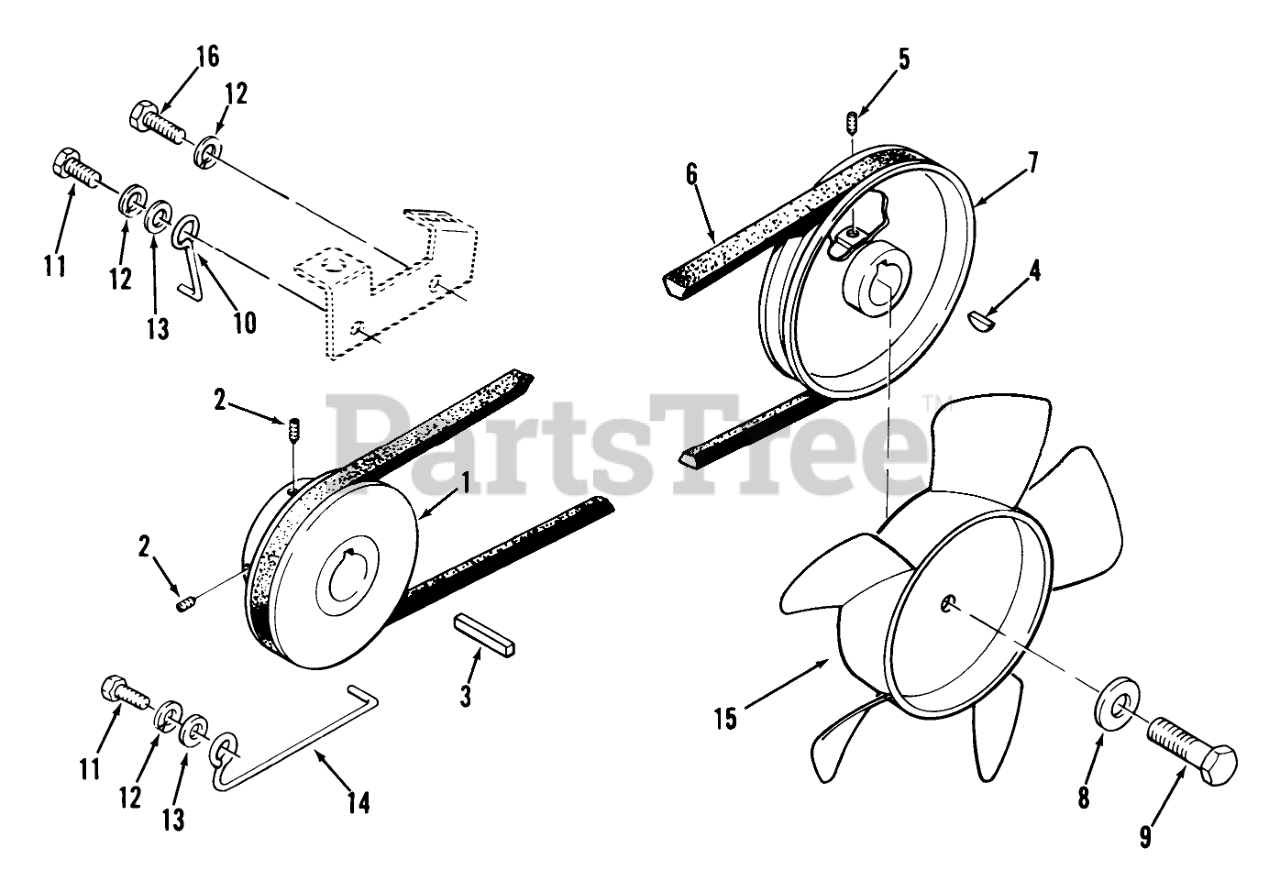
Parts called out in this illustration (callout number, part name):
1	Engine Drive Pulley C-105, C-125, C-145, C-165, C-175 Twin Only
1	Engine Drive Pulley C-85 Only
2	Set Screw
4	KEY-HI PRO
5	Set Screw
6	Drive Belt C-85, C-105, C-125, C-145, C-165 Only
6	Drive Belt C-175 Twin Only
7	PULLEY-TRANSMISSION
10	Belt Guide-Top
11	7/16-14 x 1 1/4 Bolt
11	Bolt 3/8-16 X 3/4 C-85 Only
12	Lockwasher 7/16 C-105, C-125, C-145, C-165, C-175 Twin Only
12	Lockwasher 3/8 C-85 Only
13	Washer 7/16 C-105, C-125, C-145, C-165, C-175 Twin Only
13	Washer 3/8 C-85 Only
14	Belt Guide-Bottom
16	Bolt 7/16-14 X 1-1/4 C-105, C-125, C-145, C-165, C-175 Twin Only
16	Bolt 3/8-16 X 1-1/4 C-85 Only
